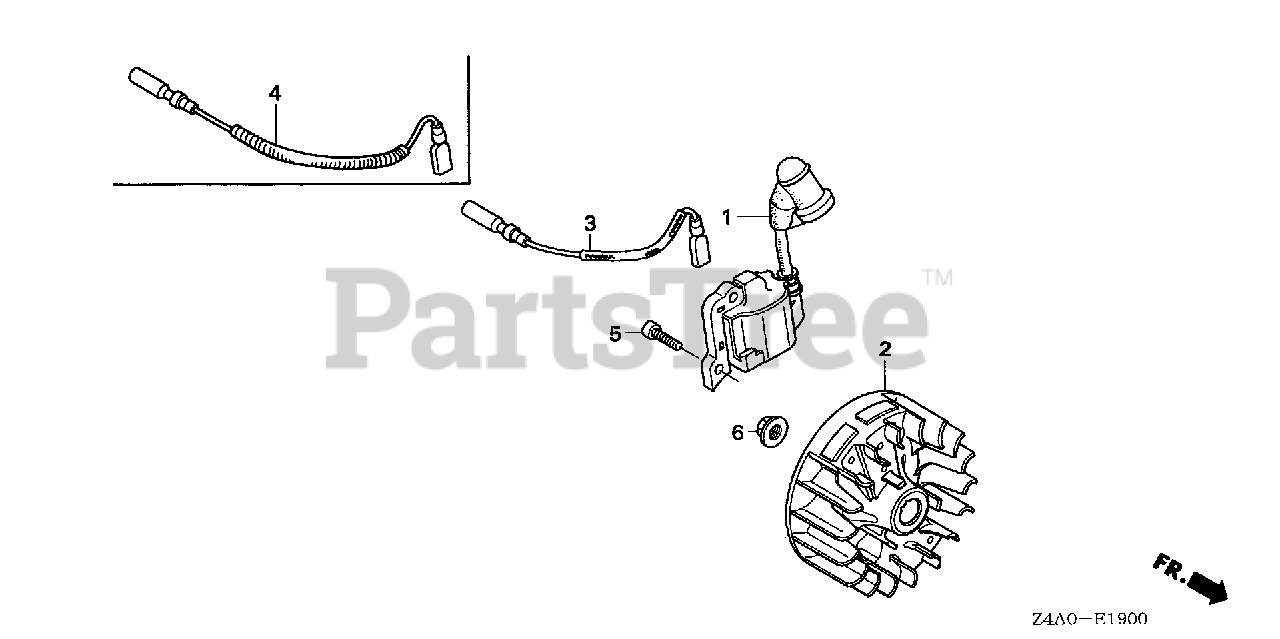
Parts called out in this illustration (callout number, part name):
1	COIL ASSY., IGNITION
3	WIRE, STOP SWITCH
5	BOLT, SOCKET (4X14)
6	NUT, FLANGE (7MM)
